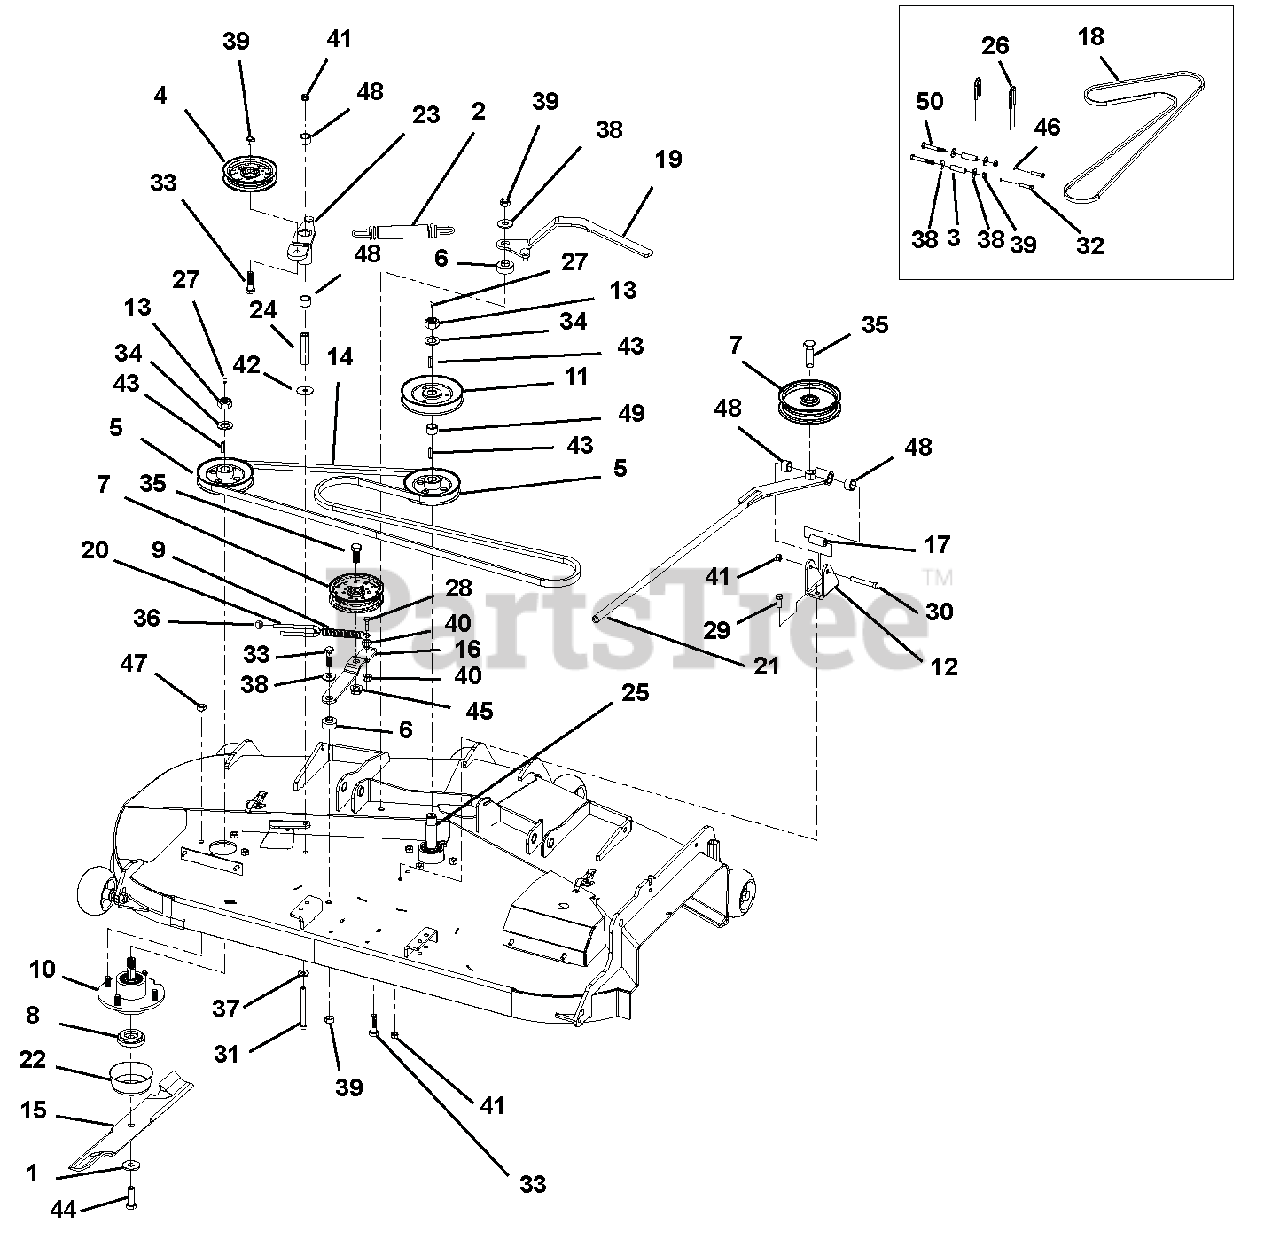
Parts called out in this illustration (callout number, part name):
1	WASHER, M14XM40XM4.5 FLAT Y
2	SPRING, EXT 1.18X.177X7.50 Y
3	TUBE, RD .750 X.125W X 2.469
4	PULLEY, V-BELT 5.00X.510 W/BRG
5	SHEAVE, 5.00 SPINDLE (1.00ID)
6	SPACER, .516 X .750 X .853 Y
7	PULLEY, FLAT 5.00X.635 W/BRG
8	SPCR, BLADE
9	SPRING, EXT .750X.125X4.50 Y
10	ASSY, SPINDLE 1"SHORT SHFT S/O
11	PULLEY, V-BELT 6.57X1.00 W/KEY
11	PULLEY, V-BELT 7.21X1.00 W/KEY
12	PLATE, PIVOT ANCHOR BENT
13	NUT, 1-14 THIN PATTERN NYLOCK
14	BELT, HB 123.0 OC PES OHR
14	BELT, B112
15	BLADE, 20.940 X 1.00 LIFT
15	BLADE, 19.000 X 1.00 LIFT
16	ARM, BELT TENSIONER
16	ARM, BELT TENSION 54"
17	SPANNER
18	BELT, HB 114.9 EL AMD
19	WLDT, TENSION ARM
20	U-BOLT, RD .63X4.50X3/8-16SP Y
21	ASSY, OFFSET ARM
22	CAP, SPINDLE
23	ASSY, DECK IDLER
24	TUBE, RD .750 X .156 X 3.05
25	ASSY, SPINDLE 1" LONG SHFT S/O
26	U-BOLT, RD 1.00X3.00X3/8-16 Y
27	FTG, 1/4-28 STRGT GREASE ZERK
28	BOLT, 5/16-18X1.25 HEX 5 Y
29	@BLT-HEX .38-16X1.00 GR5 YWZC
30	@BLT-HEX .38-16X2.50 GR5 YWZC
31	@BLT-HEX .38-16X4.25 GR5 YWZC
32	@BLT-HEX .44-14X1.75 GR5 YWZC
33	@BLT-HEX .50-13X1.75 GR5 YWZC
34	WASHER, 1.062X1.75X0.100 Y
35	@BLT-HEX .62-11X1.50 GR5 YWZC
36	@NUT-HEX .38-16 YWZC
37	@WSHR-FL-STL.438X1.00X.083 YWZ
38	@WSHR-FL-STL.563X1.38X.109YWZC
39	NUT-LK-CONE .50-13 GR C YWZC
40	@NUT-SPNLK-FLG .312-18 YWZC
41	NUT-LK-FLG .375-16 PL
42	WSHR-FL-STL .380X1.50X.062 YWZ
43	KEY, .250 X .250 X 1.00 SQ
44	BLT-HEX .56-12X1.75 HEX 8 YWZC
45	SRATD FLNG HEX NUT 5/8-1 44412
46	NUT-FLANGED WHIZ .438-14 YWZC
47	HEX NUT 7/16-20 UNF CP 15609
48	BRG, SLV .753X.878X.750
49	SPACER, ?1.01 X ?1.25 X .635 Y
50	BOLT, 1/2-13X3.50 HEX 5 Y
